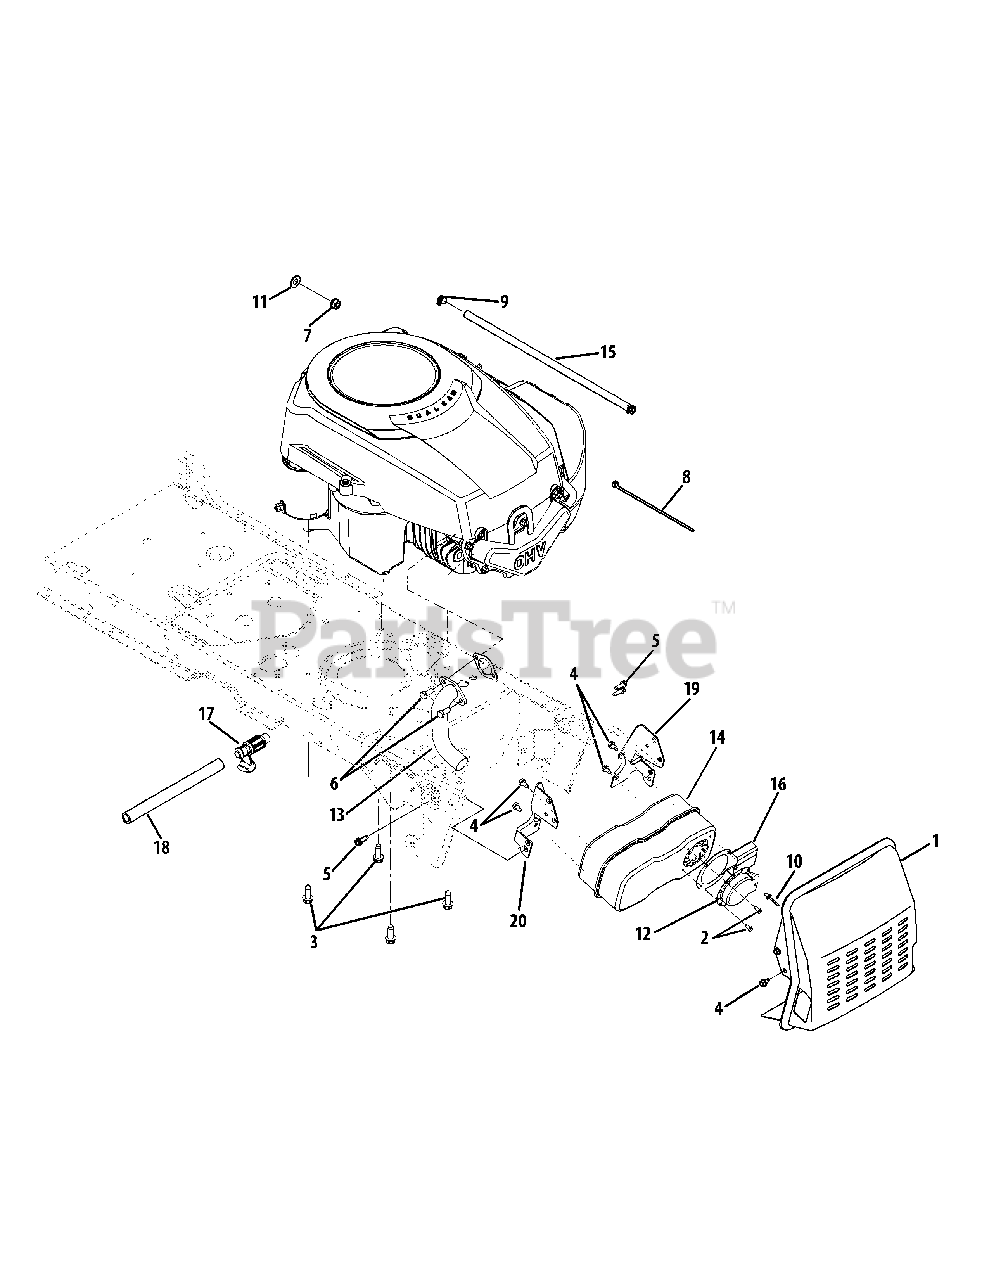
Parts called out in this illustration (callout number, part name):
1	Muffler Shield
2	Hex Washer Screw, #8-18 x .5
3	Hex Screw, 3/8-16 x 1.0
4	Hex Washer Screw, 1/4-20 x .5
5	Hex Washer Screw, 1/2-20 x .625
6	Hex Screw, 5/16-18 x .75
7	Hex Lock Nut, 3/8-16
8	Cable Tie
9	Hose Clamp
10	Pop Rivet, .188 x .3
11	Flat Washer, .406 x .875 x .059
12	Muffler Deflector
13	Pipe Exhaust
14	Single Inlet Muffler
16	Muffler Deflector
17	Oil Drain Valve
18	Oil Drain Extension Hose
19	LH Muffler Bracket
20	RH Muffler Bracket
NS	Fuel Line Cable Tie, 7.5
